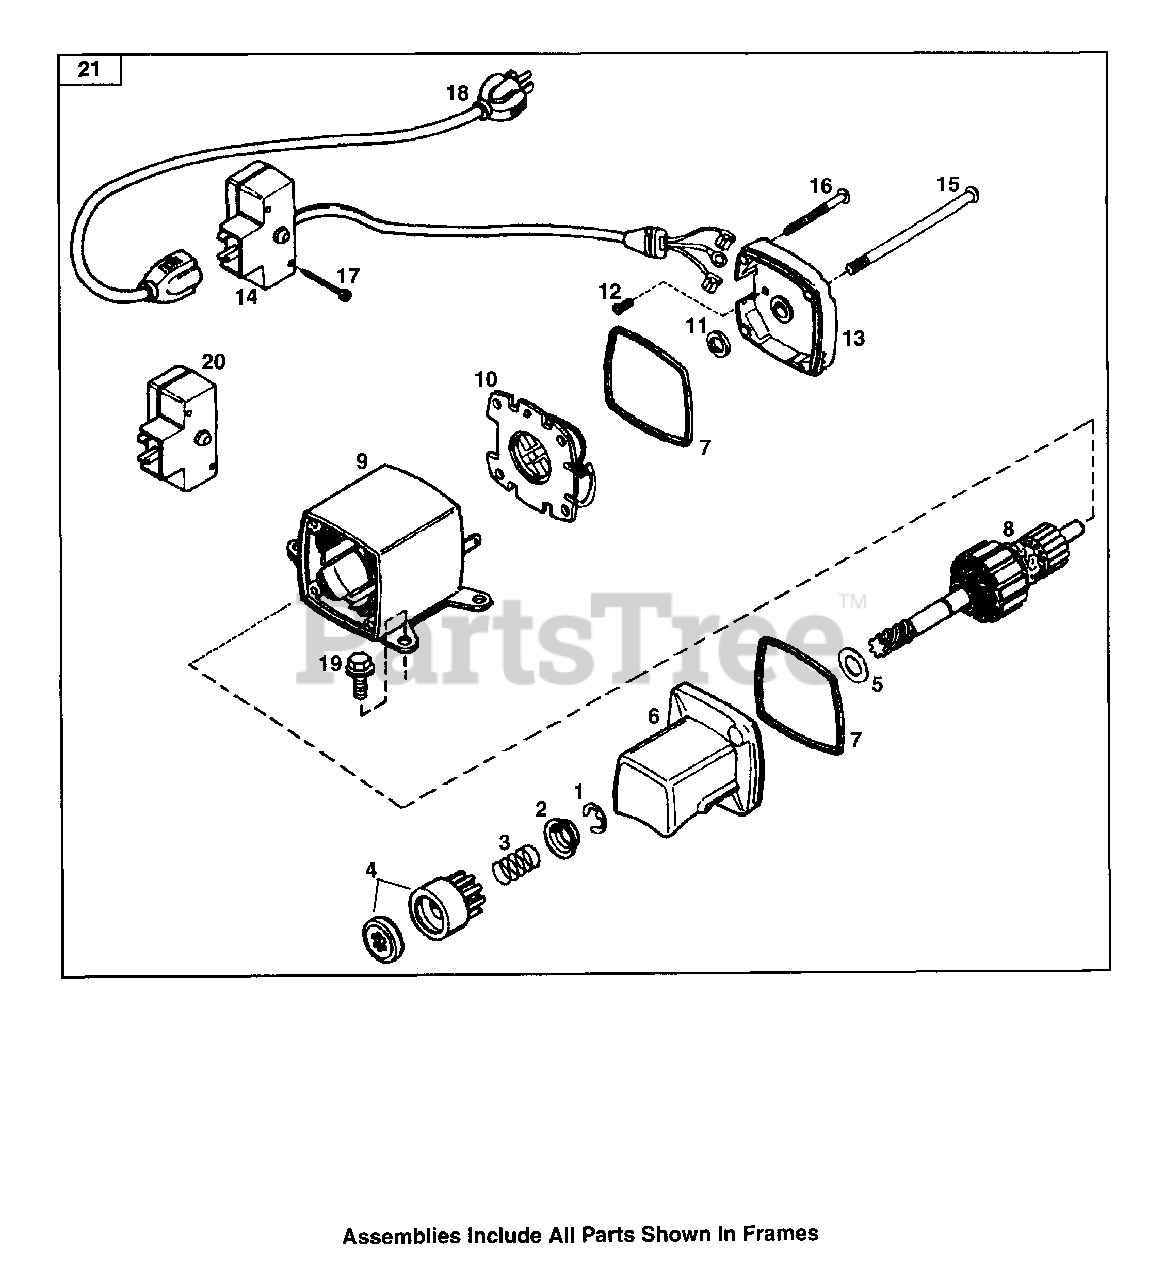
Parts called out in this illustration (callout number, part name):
1	Retainer Ring
2	Spring Retainer
3	Anti-Drift Spring
4	Nut & Gear
5	Thrust Washer
6	Drive End Cap Ass'y
7	110" Ring
9	Housing Ass'y
10	Brush & Spring Card Ass'y
11	Thrust Washer
12	Ground Screw
13	Commutator End Cap Ass'y
14	Switch Box Ass'y
15	Case Bolt
16	Grounding Screw
17	Screw, 6-32 x 2-1/2"
18	Extension Cord
19	Screw, Torx T 30, 1/4-20 x 23/32"
20	Switch Repair Kit
21	Electric Starter (110 Volt)
